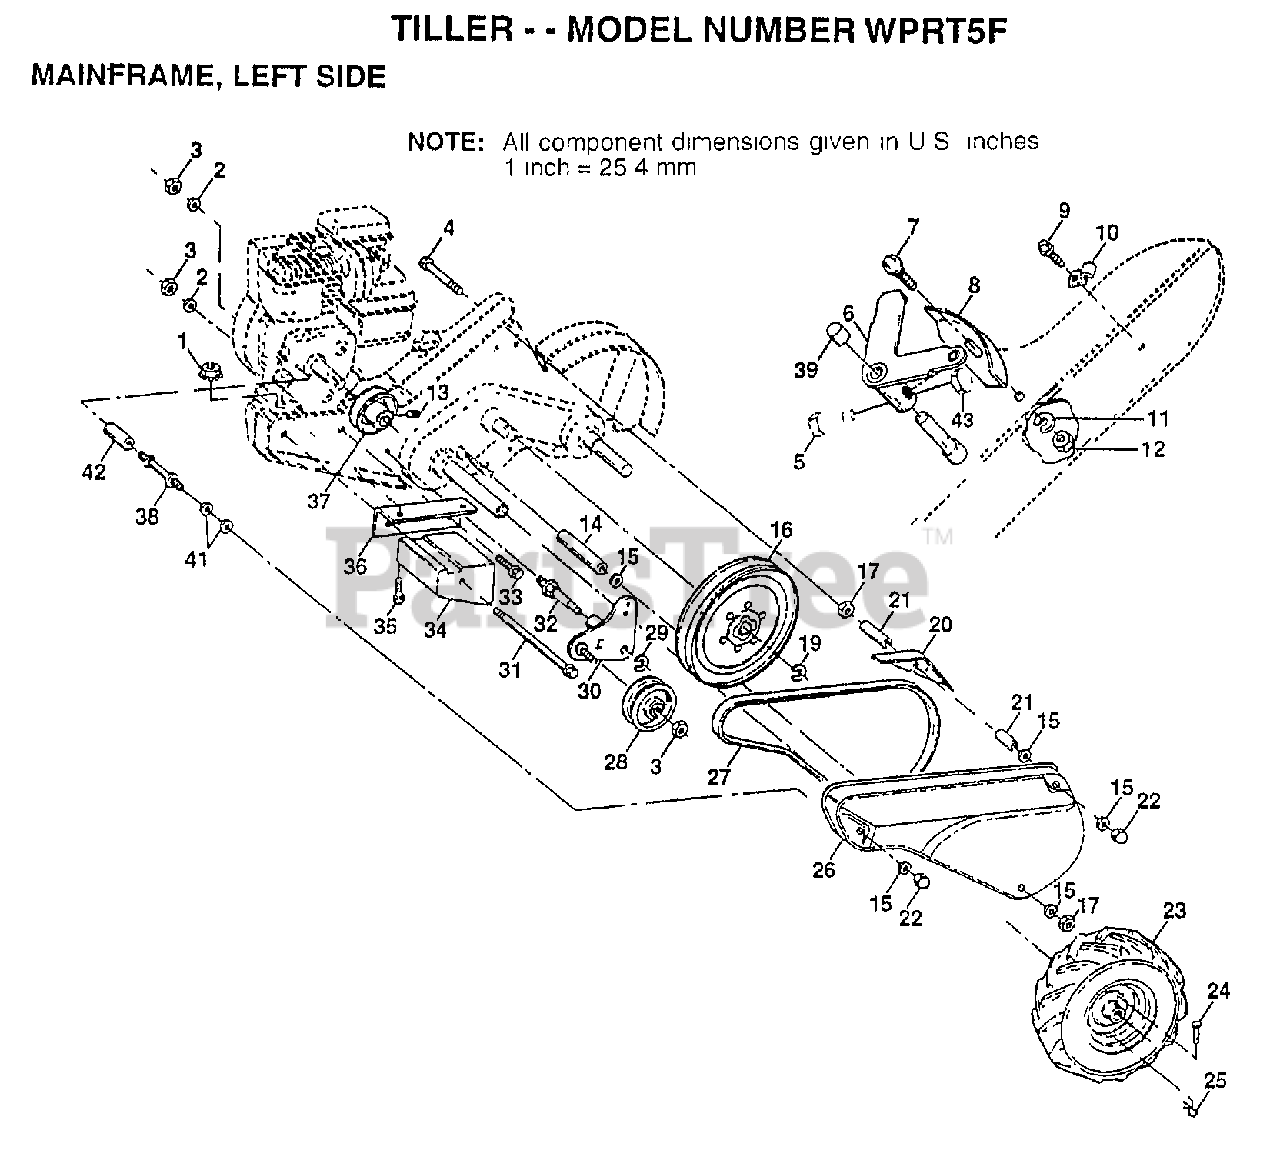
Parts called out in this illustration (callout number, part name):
2	LOCKWASHER
3	NUT.HEX.3/8-16UNC
4	BOLT TI
5	"SCREW-LEVER,SHI"
6	LEVER ASM CRT
7	BOLT
8	PANEL TI
10	CONDIUT CLIP T
11	LOCKWASHER
13	SET SCREW
14	SPACER
15	WASHER
16	SHEAVE.TRANS.
17	NUT.HEX.5/16-18
20	GUARD CRT
21	SPACER.SPLIT
22	NUT TI
23	TIRE TI
24	RIVET.DRILL.1.75
25	RETAINER M
27	BELT-V
28	PULLEY-IDLER TI
29	KLIP RING
31	BOLT CRT
32	SHIFT ARM CRT
33	BOLT
34	COUNTERWEIGHT CRT
35	BOLT
36	BRACKET LH CRT
37	ENGINE PULLEY
38	STUD.GUARD.BELT
39	CAP PLUNGER BLACK
41	WASHER
43	LOCKNUT
